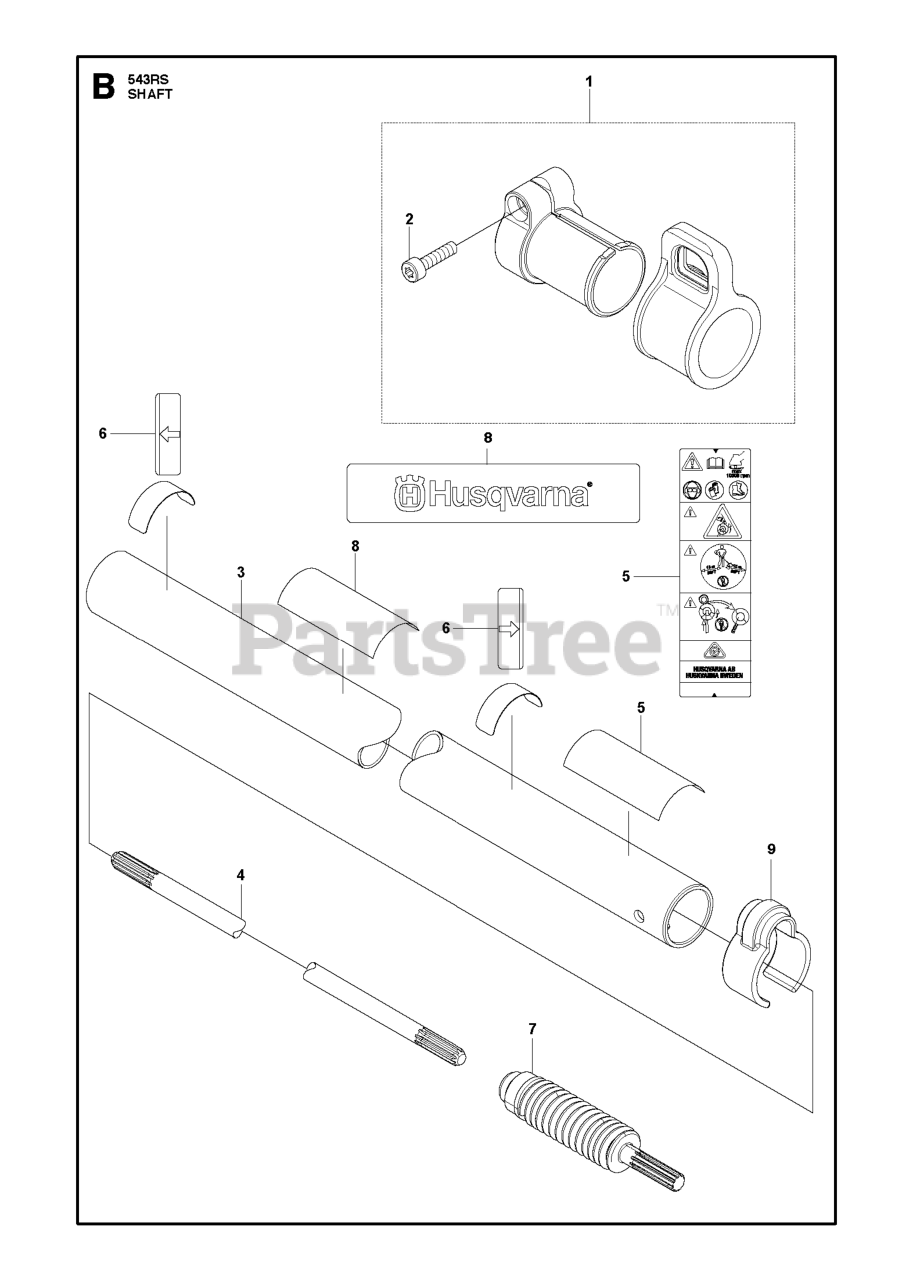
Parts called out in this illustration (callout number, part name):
1	HANGER ASSY.
2	BOLT
9	CLAMP
